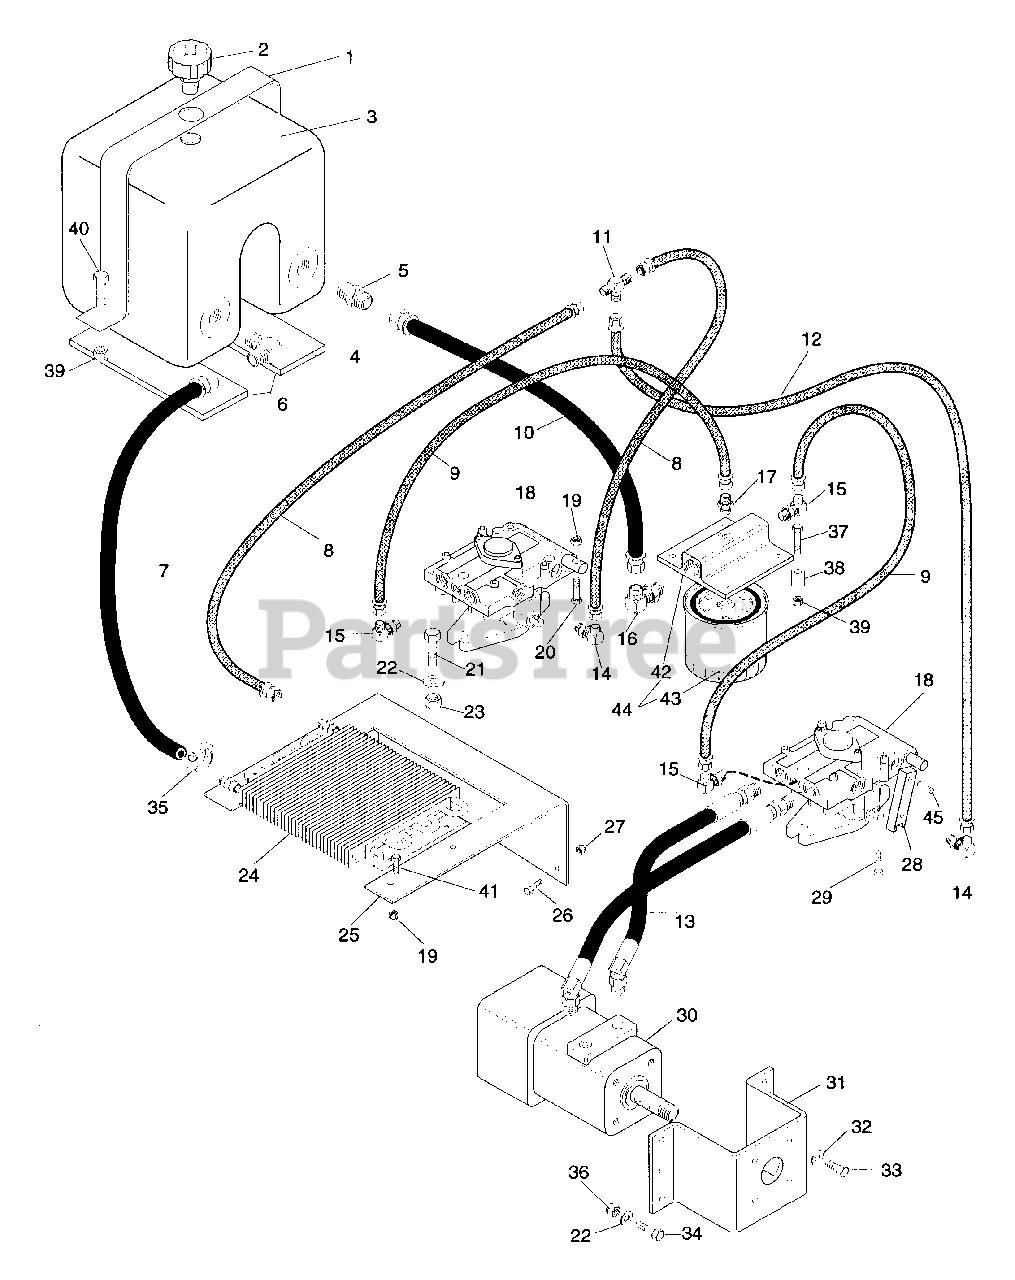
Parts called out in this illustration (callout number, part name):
1	Strap, Tank
2	Cap, Filter
3	Tank, Hydraulic
4	Adptr - .75 - .875
5	Adapter, Hyd.
6	Pad, Gas Tank
7	Hose, Hyd Cooler To Tank
7	Hose Asm, Oil Cooler to Tank
8	Hose, Hyd Valve To Tank
9	Hose, Oil Filter To Pump
10	Hose, Hyd Tank To Filter
11	Adpt Tee.56 18
12	Hose, Pump To Tee
13	Asm, Show Whl Mtr To Pump
13	Asm, Hose Whl Mtr To Pump
14	Adpt 2503-6-6
15	Adpt 2503-4-4
16	Adptr - Pipe .75 - 16 "O" Ring M37
17	Adpt 0503-4-4
18	Variable Displace Pump
19	Nut - Lk - Nyl .250 - 20 Pl
20	Blt - Hex .25 - 20 x 2.00 Pl Gr 5
21	Blt - Hex .38 - 16 x 1.125
22	Wshr - Fl - Stl .406 x .812 x .065
23	Nut - Lk - Ctr .375 - 16 Typ N
24	Cooler, Oil
25	Brkt, Oil Cooler Kohler
25	Brkt, Oil Cooler B & S
26	Blt - Hex .38 - 16 x 1.125
27	Nut - Lk - Nyl .375 - 16 Pl
28	Arm, Pump Actuating
29	Scr - Cap 10 - 24 x .75 Hex Sc
30	Motor, Hyd Wheel
31	Brkt, Wheel Motor
32	Wshr - Lock .375 x .094 Med Pl
33	Blt - Hex .380 - 16 x .875
34	Blt - Hex .38 - 16 x 1.00 Pl Gr 5
35	Clamp, .88 Dia. Hose
36	Nut - Lk - Nyl .375 - 16 Pl
37	Blt - Hex .31 - 18 x 2.00 Pl Gr 5
38	Bush., S .328 x .462 x 1.00 St
39	Nut - Lk - Nyl .312 - 18 Pl
40	Blt - Hex .31-18 x .75 Pl Gr 5
41	Blt - Hex .25 - 20 x .63
42	Asm, Head
43	Element
44	Asm, Spin-On Lube
45	Pin, Dowel
